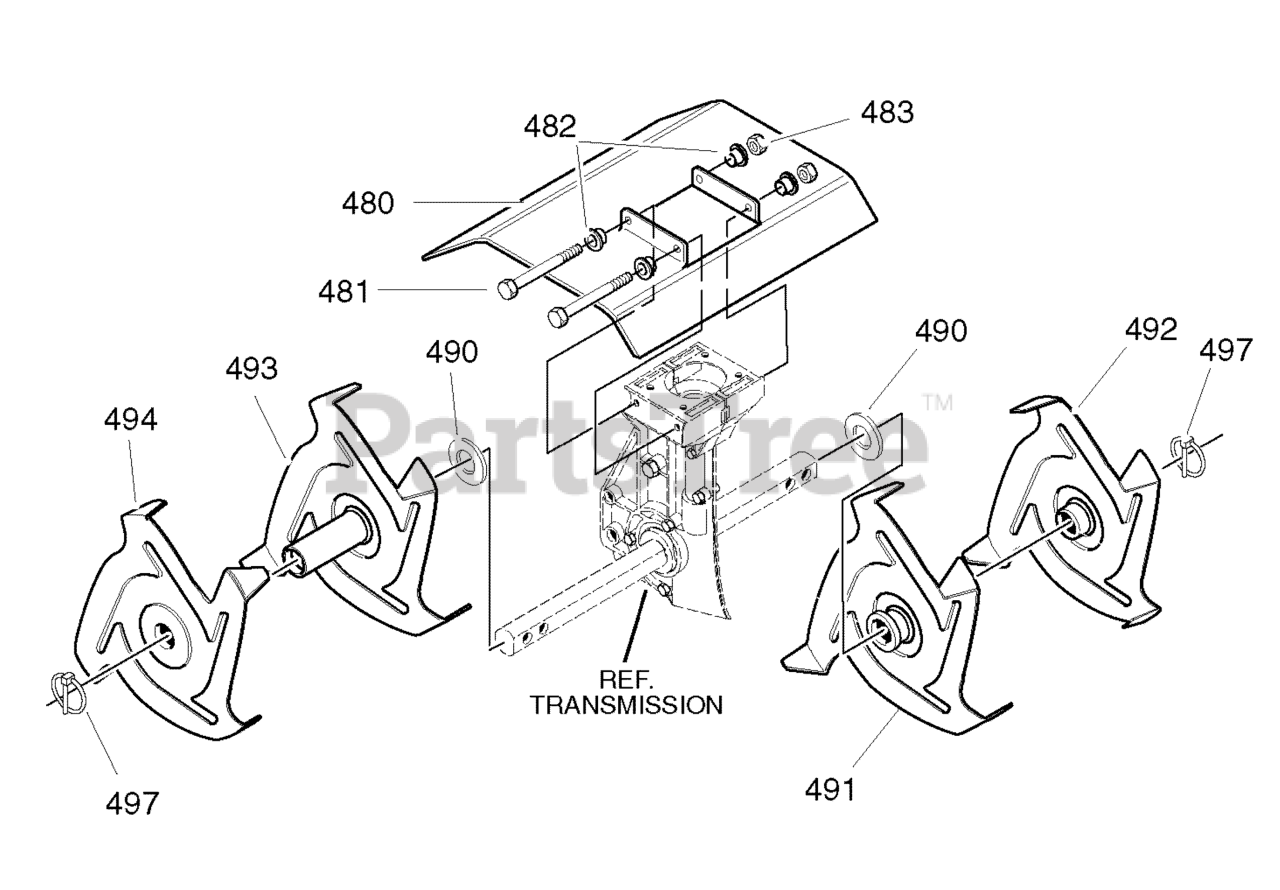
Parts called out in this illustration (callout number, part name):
480	SHIELD, Tine
481	SCREW, 1/4-20x5.50
482	SPACER, Flange
483	NUT, 1/4-20
490	WASHER, Felt
491	TINE ASSEMBLY, Inner LH
492	TINE ASSEMBLY, Outer LH
493	TINE ASSEMBLY, Inner RH
494	TINE ASSEMBLY, Outer RH
497	PIN, Latch
